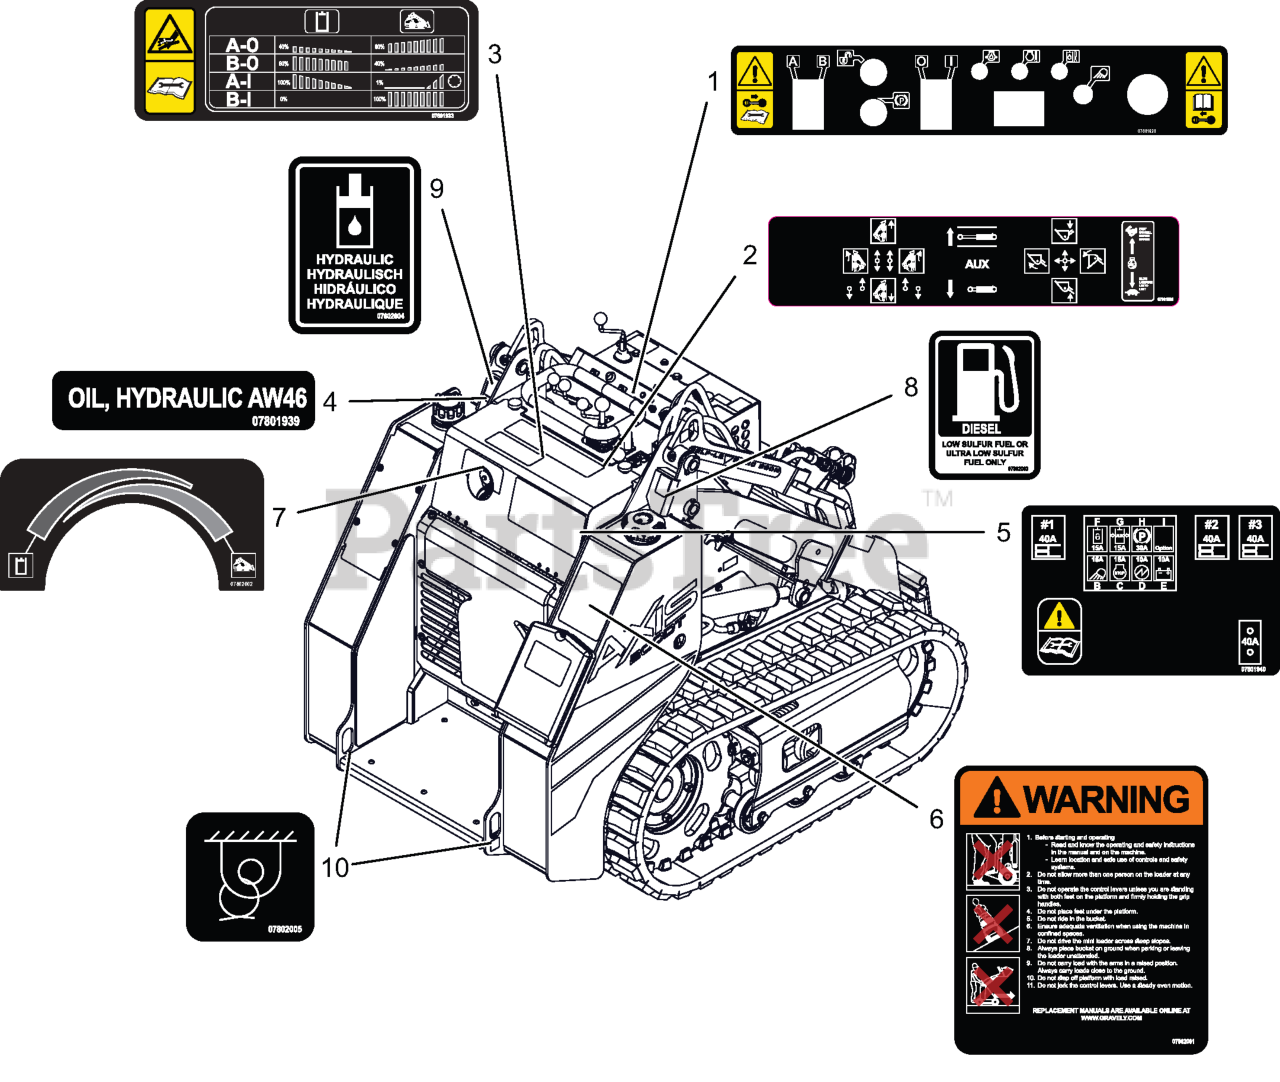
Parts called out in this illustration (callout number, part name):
1	DECAL, DASH PANEL
2	DECAL, CONTROLS
3	DECAL, FLOW CONTROL
4	DECAL, OIL HYD AW46
5	DECAL, FUSE PANEL
6	DECAL. WARNING OPERATION
7	DECAL, COMBINER FLOW
8	DECAL, DIESEL FUEL
9	DECAL, OIL RESERVOIR
10	DECAL, TIE DOWN
